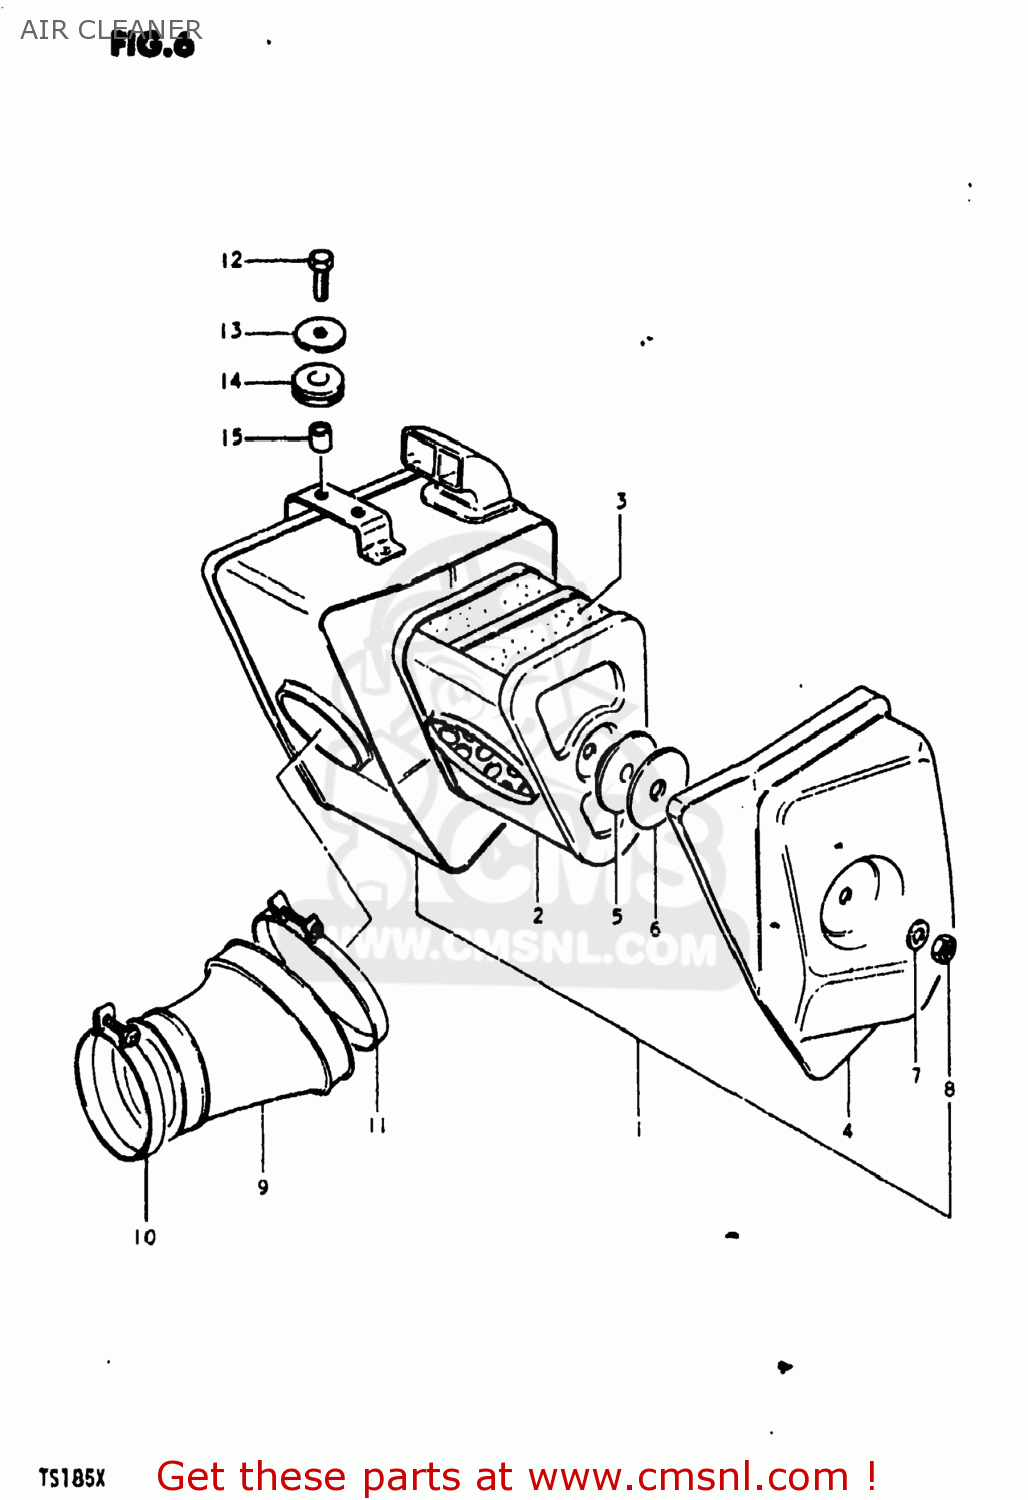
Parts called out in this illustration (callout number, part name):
1	CLEANER ASSEMBLY,AIR
2	FILTER ASSY,AIR CLEANER
3	FILTER
4	CAP
5	SEAL
6	SPACER
7	WASHER
8	NUT
9	TUBE,AIR CLEANER OUTLET
10	CLAMP
11	CLAMP
12	BOLT, UPPER
13	WASHER (6.5X20X1.2)
14	CUSHION
15	SPACER (7X9X7)
